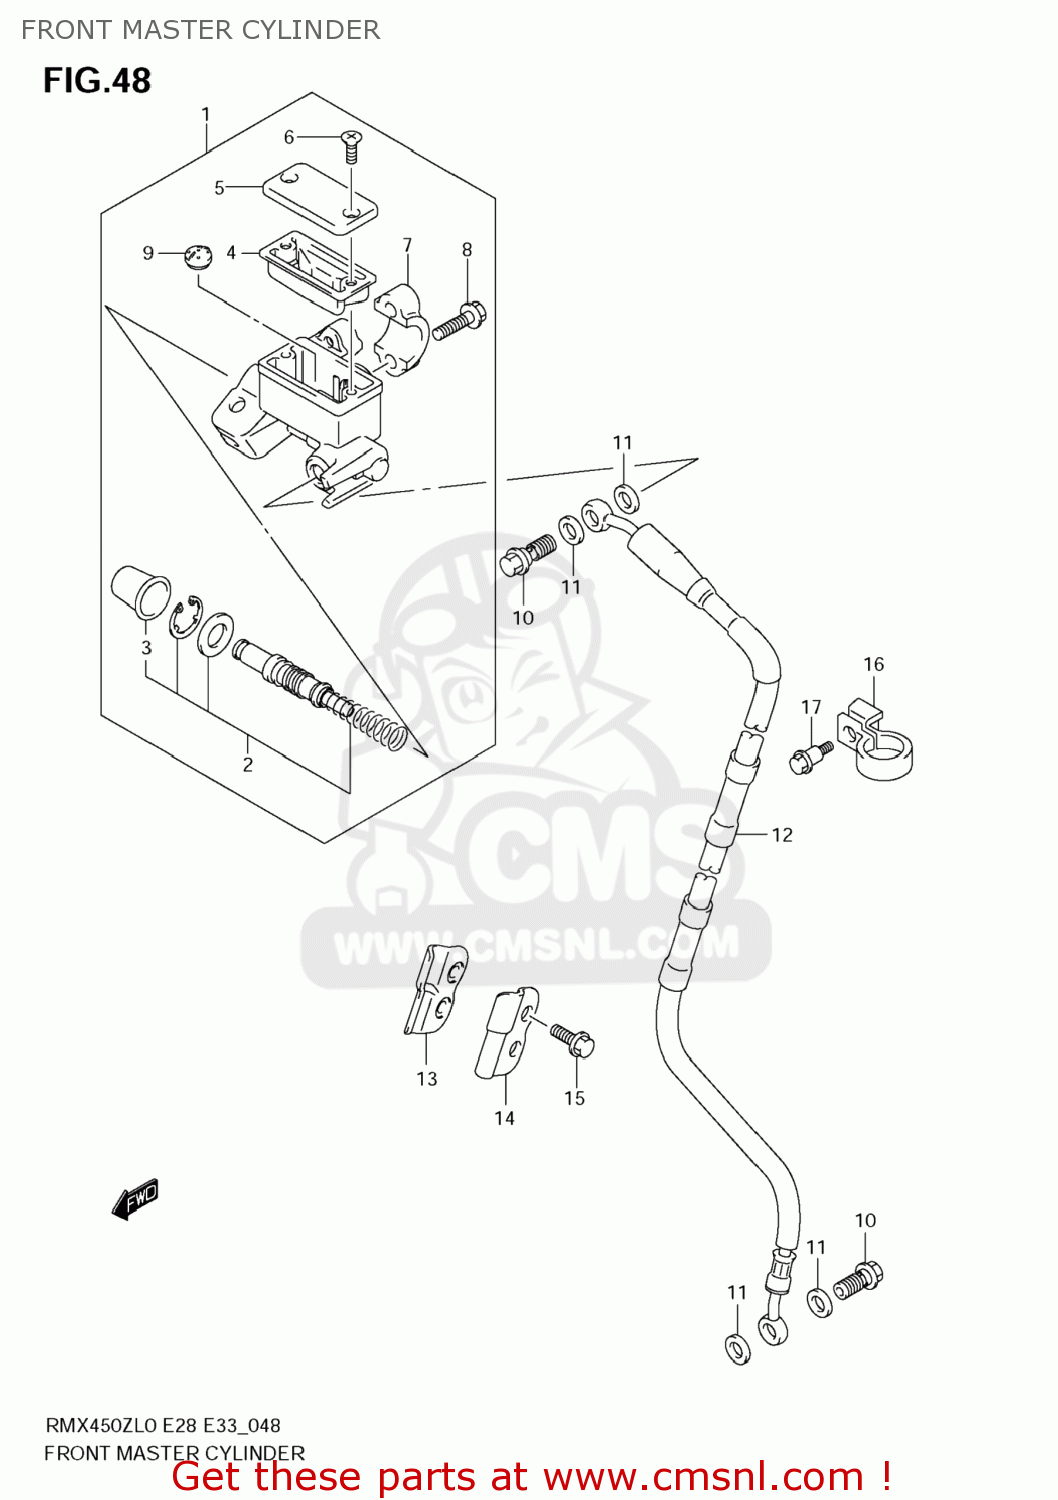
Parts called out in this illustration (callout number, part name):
1	CYLINDER ASSY,FR MASTER
2	PISTON & CUP SET
3	BOOT
4	DIAPHRAGM
5	CAP
6	SCREW
7	HOLDER
8	BOLT
9	SEPARATOR
10	BOLT UNION
11	WASHER(10X15X1.5)
12	HOSE,FR BRAKE
13	CLAMP,FR BRAKE HOSE
14	CLAMP,FR BRAKE HOSE
15	BOLT(6X16)
16	GUIDE,FR BRAKE HOSE
17	BOLT(6X20.5)
